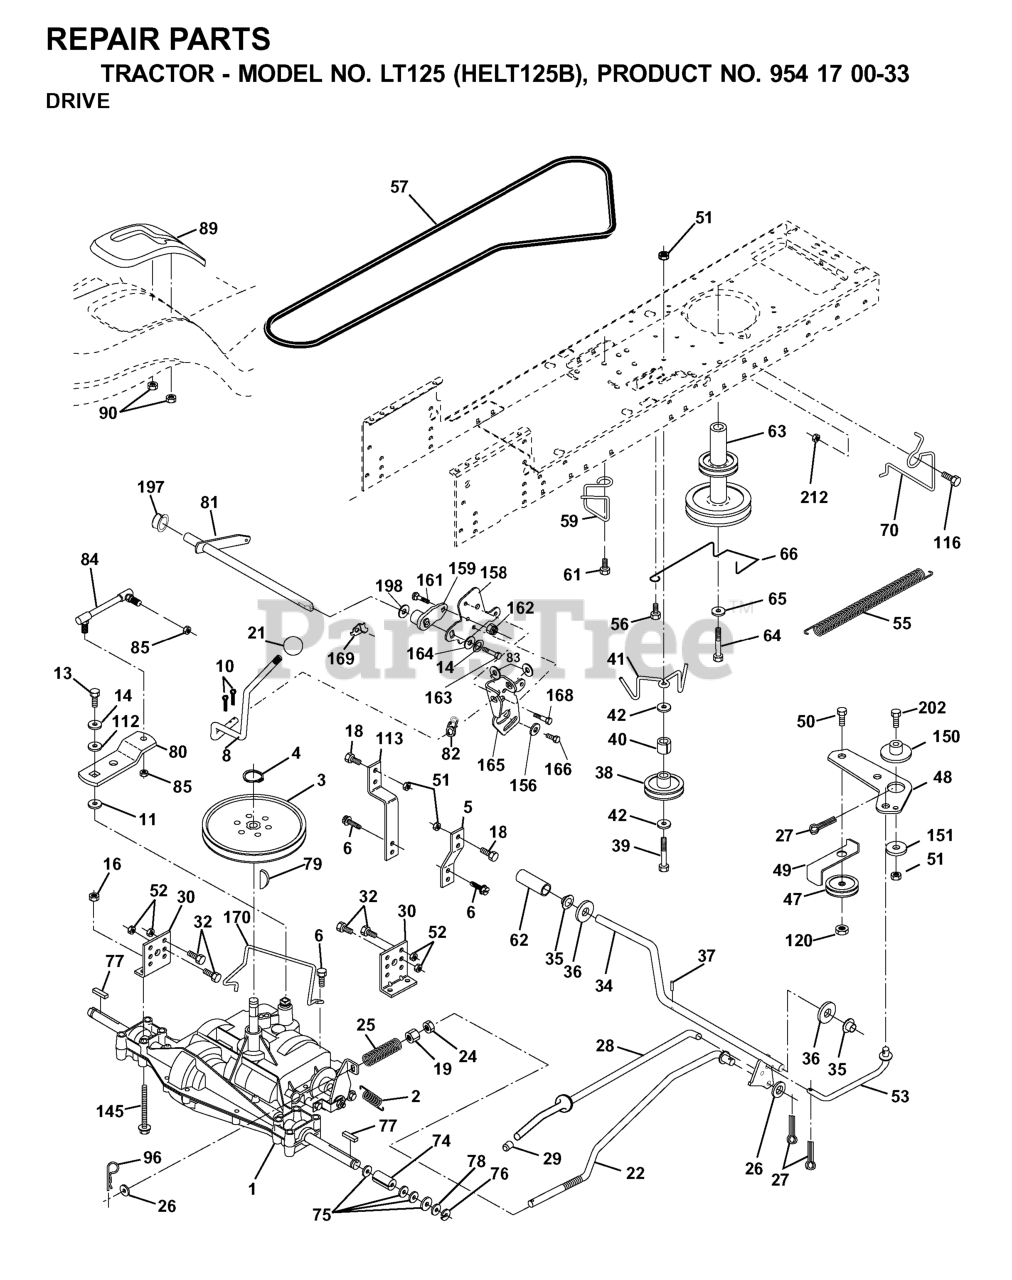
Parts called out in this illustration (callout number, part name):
2	SPRING,BRAKE RETURN
3	PULLEY TRANS
4	RETAINING RING LT
5	STRAP TORQUE
6	SCREW 5/16"
8	ROD SHIFT FENDER ADJUST STLT
10	PIN COTTER
11	WASH-SHFT PLT LT
13	BOLT 1/4-28X3/4
14	LOCKWASHER
16	NUT.71038.31-18.HEX.NYLOCK
19	NUT
21	KNOB.DUCKHEAD.1/2
24	NUT
25	SPRING ROD LT
26	WASHER
27	COTTER PIN
28	ROD, PARKING BRAKE
29	PLUNGER CAP
30	BRKT, MOUNT TRNSAXLE
32	BOLT
34	SHAFT, FOOT PEDAL
35	BEARING.NYLON
37	DRIVE PIN
38	PULLEY.FLAT
39	BOLT
40	SPACER, SPLIT
41	KEEPER, BELT IDLER
42	WASHER
47	IDLER PULLEY
48	BELLCRANK, CLUTCH
49	RETAIN BELT
50	BOLT
52	LOCKNUT
53	LINK, CLUTCH LT
55	SPRING, RETURN LT
56	SCREW THDROL 3/8-16 X 1-1/2
57	V-BELT
59	KEEPER, BELT CENTER
61	SCREW 3/8-16X3/4
62	COVER, PEDAL (1 2)
63	ENGINE PULLEY
64	BOLT
65	LOCKWASHER
66	KEEPER BELT ENGINE
70	KEEPER BELT ENG
74	SPACER AXLE
77	SQUARE KEY
79	KEY STD (1373) DANA
81	SHAFT ASM CROSS TAPERED
82	SHIFT SPRING
83	WASHER
84	LINK.TRNSAXLE
85	NUT LOCK CENTER 1/4 -28 FNTHD
90	NUT.PUSH.3/16
96	RETAINER M
113	STRAP TORQUE LH LT
116	BOLT D
120	NUT LOCK FLG 3/8-16 UNC
150	SPACER, RETAINER
151	WASHER 12/32X2X10GA
156	WASHER.SRRTD.5/16
158	BRACKET
159	HUB
161	BOLT
162	NUT.CROWNLOCK.1/4
164	Washer 5/8 x .281 x 10 Ga.
165	RP BRACKET
168	BOLT.SHOULDER.5/16-18X
169	PLATE.FASTENING.CROSS.SHAFT
170	SPRING, RETURN LT
197	NYLINER SNAP 5/8" ID
198	WASHER.NYL.7/8IDX.105"HYD CR
212	NUT
